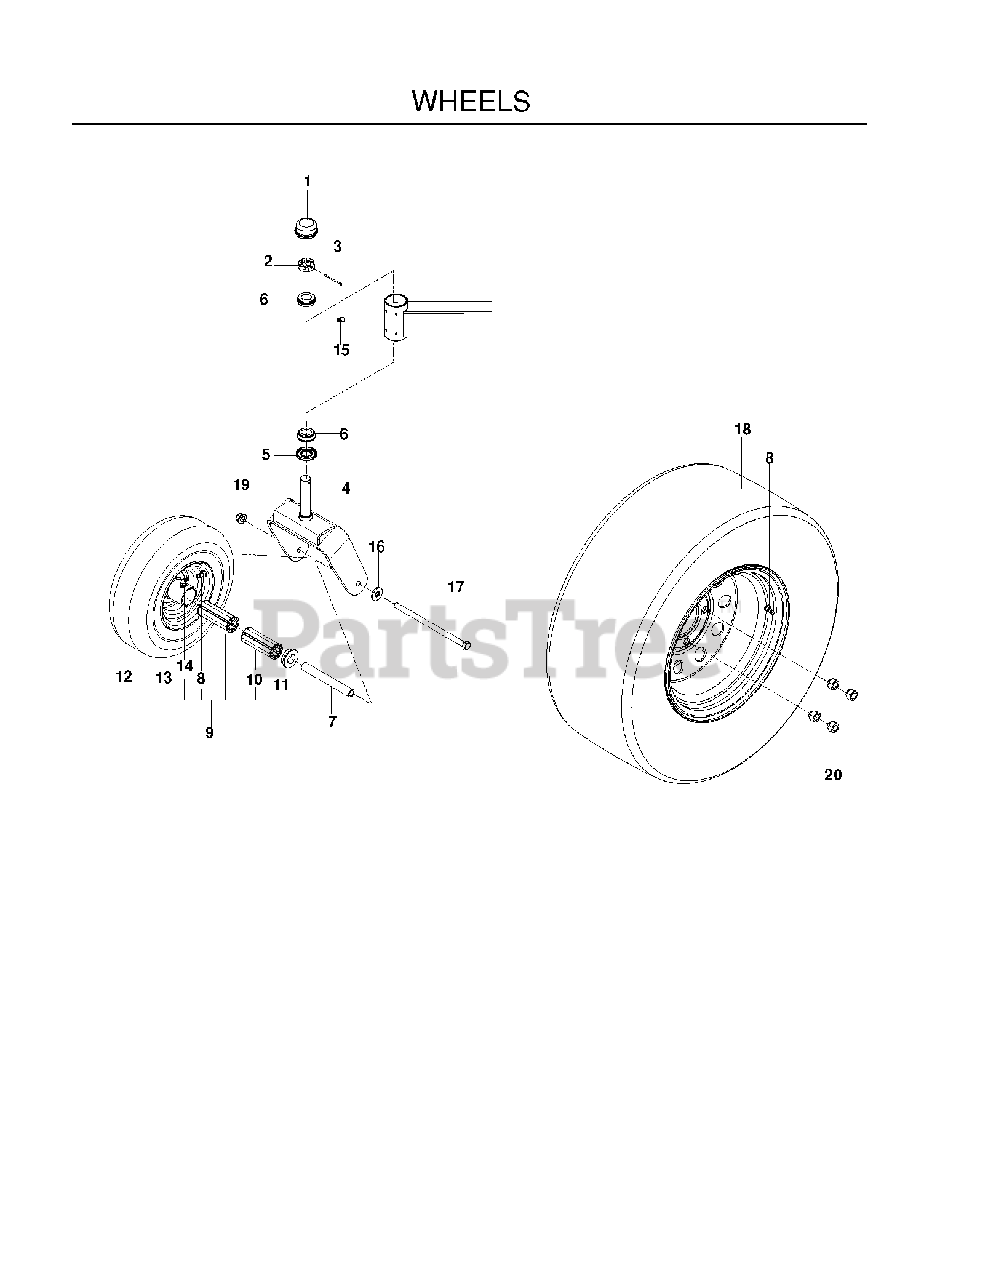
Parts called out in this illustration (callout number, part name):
1	GREASE CAP
2	NUT 1"C HEX SLOTTED
3	COTTER PIN 1/8 X 2
4	YOKE.CASTER.ORANGE
6	TAPERED ROLLER BRG
7	SPACER, PIVOT
8	VALVE STEM TR-412
9	TIRE.ASSEM.CASTER.13X6.5-6.SIL
10	ROLLER BEARING-CAGED 3 1/4'
11	BEARING RETAINER
12	TIRE.13X6.50-6.4.PLY
13	WHEEL.6X4.50.CASTER.SILVER
14	ZERK
16	WASH USS FLAT 1/2
17	HEX SCREW 1/2-13 X 9.5 GR5
18	RP WHEEL.ASM.23X10.5-12.TURFMA
19	NUT, 1/2-13 HEX FLG NYLOC ZD
20	LUG NUT 1/2F
